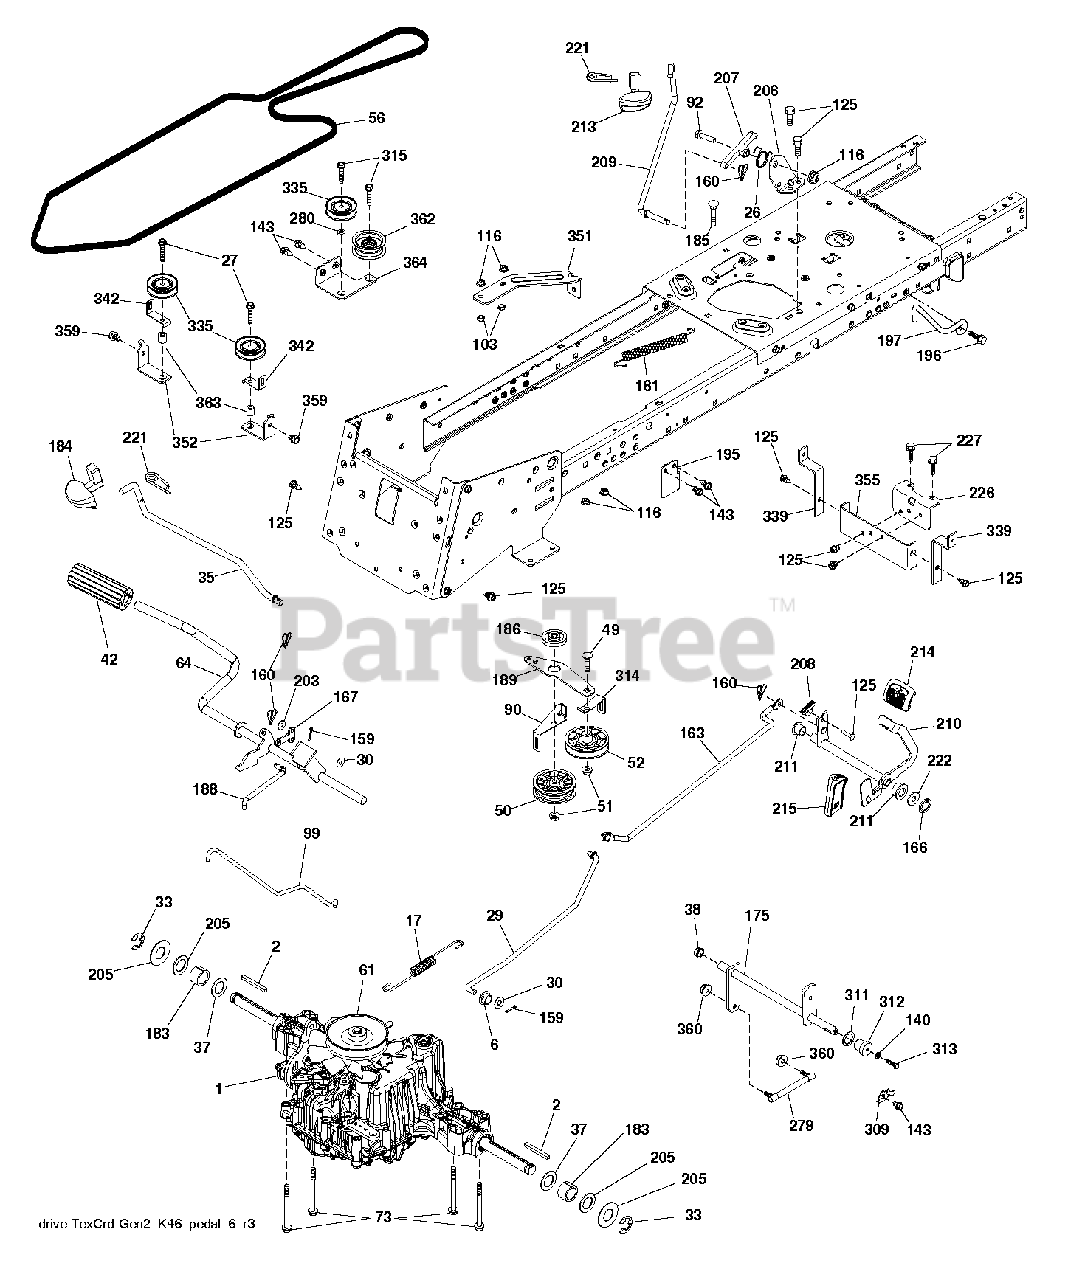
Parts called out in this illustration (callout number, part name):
17	Spring Brake
26	SPRING.RETURN.CRUISE
29	ROD ROD BRAKE K46 TCR
30	WASHER
35	ROD.BRAKE.PARTK.HUSQ.TEX
37	WASHER.HARDENED
38	NYLINER SNAP 5/8" ID
42	PEDAL COVER T
49	BOLT
50	IDLER.FLAT.910.OFFSET
51	NUT LOCK FLG 3/8-16 UNC
52	IDLER.V-GROOVE.910.OFFSET
56	BELT BELT DRIVE GROUN
61	PULLEY PULLEY INPUT F
64	SHAFT.ASM.PEDAL.BRK.CNTR
73	BOLT HEX 5/16-18 GR 5
90	KEEPER KEEPER BELT CL
92	BOLT
99	ROD ROD BYPASS CRD TE
116	NUT LOCK HEX FLANGE 5/16-18
125	SCREW
140	LOCKWASHER
159	COTTER PIN
160	RETAINER CLIP
161	SPRING, RETURN LT
163	ROD ROD CONTROL SHIFT
167	LATCH.BRAKE.SPRING
175	SHAFT SUBASM.SHAFT.CR
184	HANDLE.PARKG.BRK.HUSQ/PRED.667
186	SPACER.RETAINER
188	LINK.CLUTCH.GROUND.DRIVE
189	BELLCRANK BELLCRANK G
196	SCREW 3/8-16X1
197	LINK.CLUTCH.ANIT-ROTAT
203	WASHER
206	BRKT.MOUNT.LATCH.CRUIS
207	LATCH.CONTROL.CRUISE
208	GEAR.SECTOR.CONTROL.CR
209	ROD.CONTROL.CRUISE.GT.
210	ROCKER.ASM.PEDAL.CONTR
211	BEARING.NYLON
213	KNOB.CONTROL.CRUSIE.HU
214	PAD PEDAL FORWARD
215	PEDAL RUBBER REVERSE
221	RETAINER.SPRING.CLIP.H
222	WASHER 21/32 X 1-1/4 X 10 GA.
226	BRACKET.MOUNT.TORQUE.K46.TLT
227	SCREW
279	LINK SUBASM. LINK AND STUD
309	PLATE.FASTENING.CROSS.SHAFT
314	RETAINER KEEPER BELT
315	BOLT.5/16-18X1.25
335	PULLEY.V-IDLER.
339	STRAP STRAP TORQUE K4
351	BRACKET BRACKET DECK
352	BRACKET BRACKET IDLER
355	STRAP STRAP TORQUE K4
360	NUT NUT HEX CENTERLOC
362	IDLER.FLAT.2.25.INCH
363	SPACER SPACER 343X63X
364	BRACKET BRACKET IDLER
